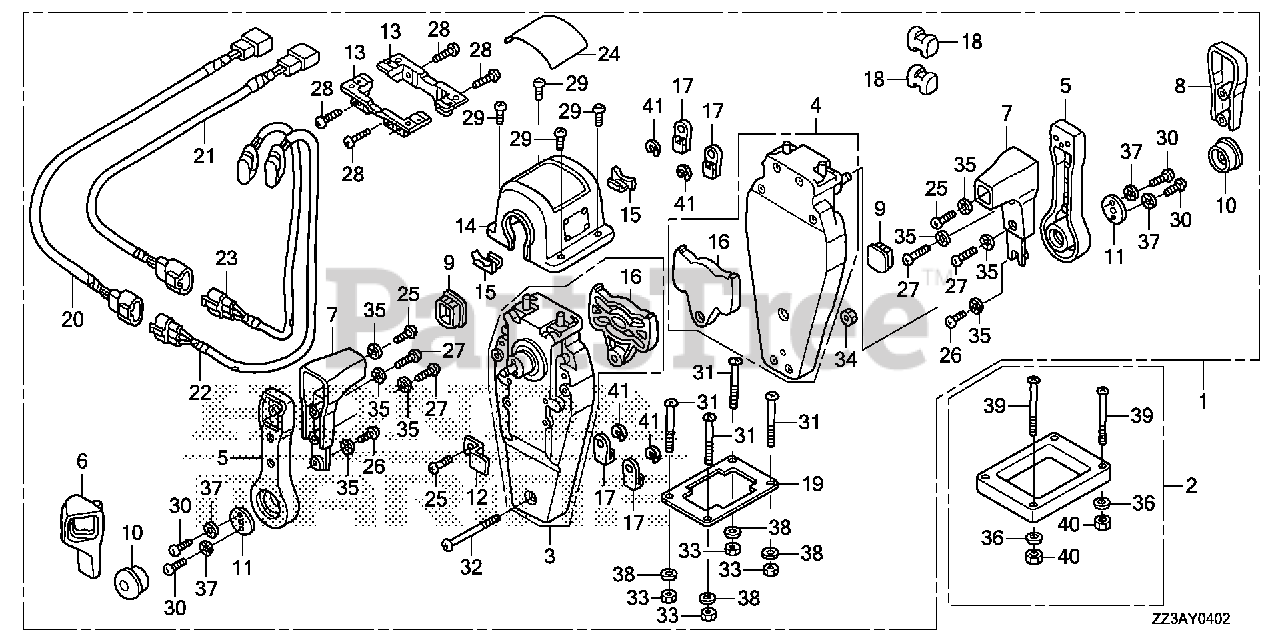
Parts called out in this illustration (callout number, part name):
1	BOX KIT, REMOTE CONTROL (TOP MOUNT DUAL)(R)
2	SPACER KIT, REMOTE CONTROL BOX (TOP MOUNT DUAL)
3	HOUSING ASSY., L. (INNER) (TOP MOUNT)
4	HOUSING ASSY., R. (INNER) (TOP MOUNT)
5	HANDLE, REMOTE CONTROL
6	COVER, L. GRIP
7	GRIP, REMOTE CONTROL HANDLE
8	COVER, DUAL GRIP
9	CAP, GRIP
10	BUTTON, THROTTLE
11	PLATE, HANDLE
12	PLATE, CABLE CLAMP
13	BRACKET, REMOTE CONTROL HOUSING
14	HOUSING, DUAL REMOTE CONTROL BOX
15	HOUSING, LEAD
16	PLATE, DWELL
17	TERMINAL, CABLE
18	SPACER, CABLE CLAMP
19	GASKET, DUAL
20	SUB-HARNESS ASSY., POWER TRIM-TILT (A)
21	SUB-HARNESS ASSY., POWER TRIM-TILT (B)
22	SWITCH ASSY., POWER TRIM-TILT (A)
23	SWITCH ASSY., POWER TRIM-TILT (B)
24	MARK, REMOTE CONTROL (DUAL)
25	SCREW, PAN (5X16)
26	SCREW, PAN (5X10)
27	SCREW, PAN (5X20)
28	SCREW, PAN (5X18)
29	SCREW, PAN (4X10)
30	SCREW, PAN (6X18)
31	SCREW, PAN (5X40)
32	SCREW, PAN (5X55)
33	NUT, HEX. (5MM)
34	NUT, HEX. (5MM)
35	WASHER, LOCK (5MM)
36	WASHER, PLAIN (5MM)
37	WASHER, LOCK (6MM)
38	WASHER, PLAIN (5MM)
39	SCREW, PAN (5X65)
40	NUT, HEX. (5MM)
41	E-RING (6MM)
